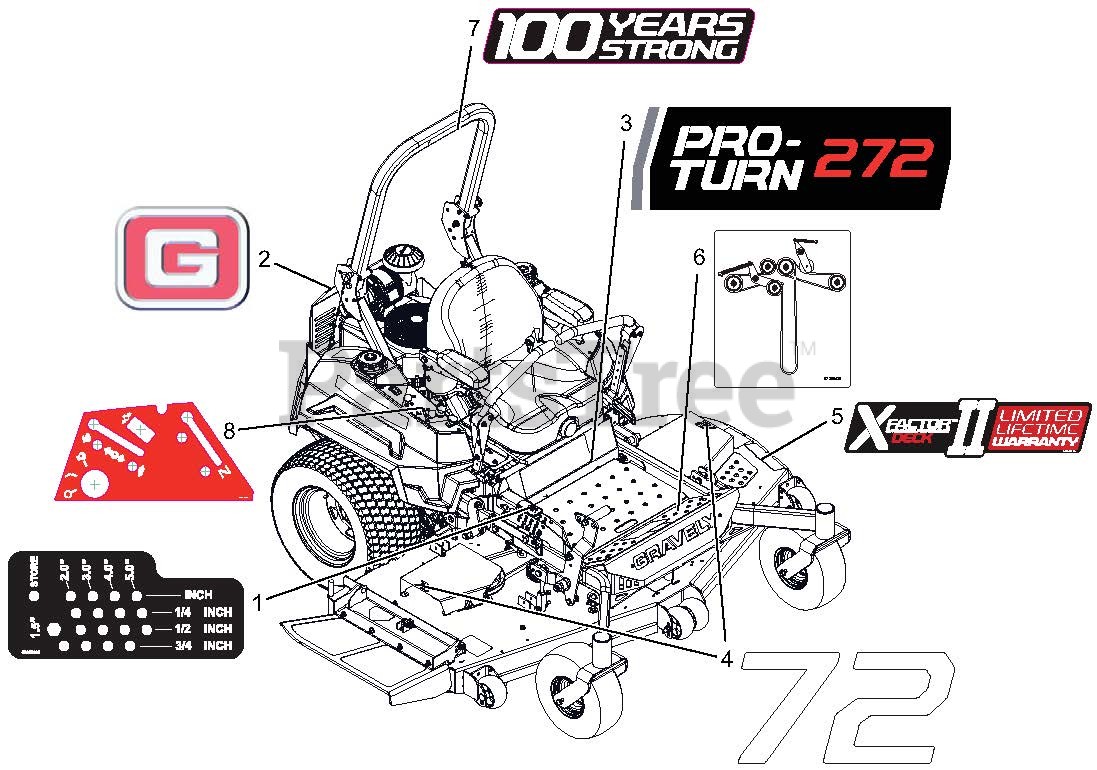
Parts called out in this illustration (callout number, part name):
1	DECAL, HEIGHT OF CUT
2	DECAL, GRAVELY BRAND
3	DECAL, PRO-TURN 272
4	DECAL, 72"
5	DECAL, X-FACTOR DECK
6	DECAL, BELT ROUTE RH BK SIDE IDLER
7	DECAL, GRAVELY 100 YEAR
8	DECAL, NON-EFI CONTROL PANEL
